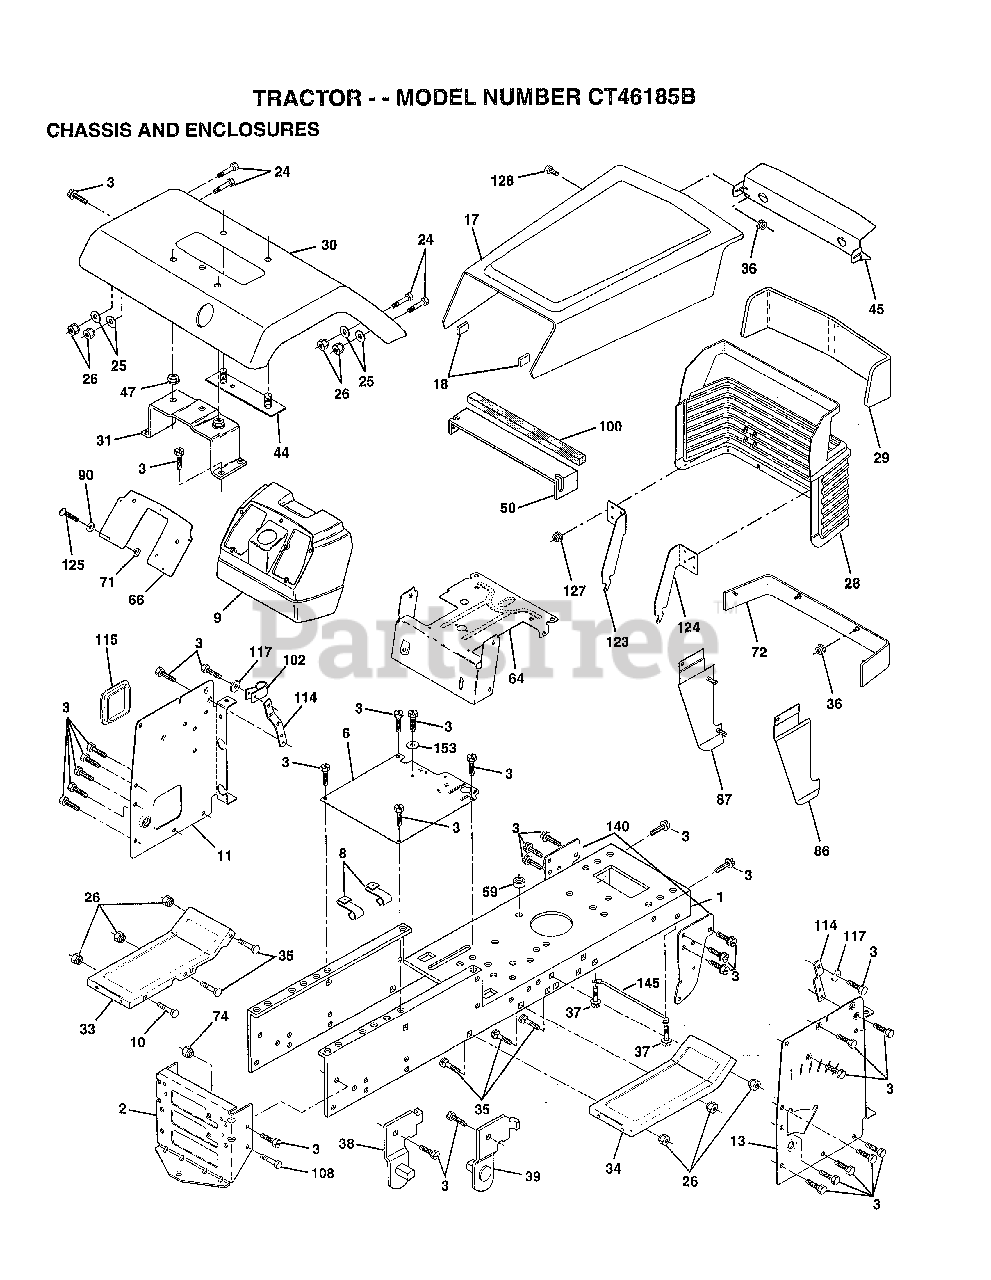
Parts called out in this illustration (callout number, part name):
3	SCREW
6	SADDLE
8	"CLIP,INSULATOR"
9	DASH.PLASTIC.BLK
11	DASHBRD.PANEL.LH
13	DASHBRD.PANEL.RH
17	HOOD/GRILLE ASM
24	BOLT
25	WASHER
26	NUT
28	GRILLE ASM WELD
30	FENDER PNT
31	BRKT.ASM.FENDER
33	FOOTREST.LH.LT/GT
34	FOOTREST.RH.LT/GT
35	BOLT
36	PAL NUT LT
37	SCREW LT
38	BRACKET ASM LH
39	BRACKET ASM RH
44	STRAP ASM FENDER
45	BEZEL.LIGHT.SLVR
47	NUT-PUSH YT
50	"BAFFLE,HOOD"
64	DASH.LOWER.LT
66	"PLATE-DASH,SILKSC"
72	STRAP FENDER ASM
86	PANEL SIDE RH ASM
87	PANEL SIDE LH ASM
90	WASHER PM
100	FOAM STRIP T
102	CLIP T
114	BRACKET.SUPT.DASH
115	COVER ACCESS
117	WASHER.SERRATED.
123	BRACKET.PICK.LH.
124	BRACKET.PICK.RH.
125	SCREW
127	PAL NUT
128	SCREW SPECIAL
140	BRKT SUSPENSION
145	"ROD POVOT,CHASSIS"
153	WASHER GT
